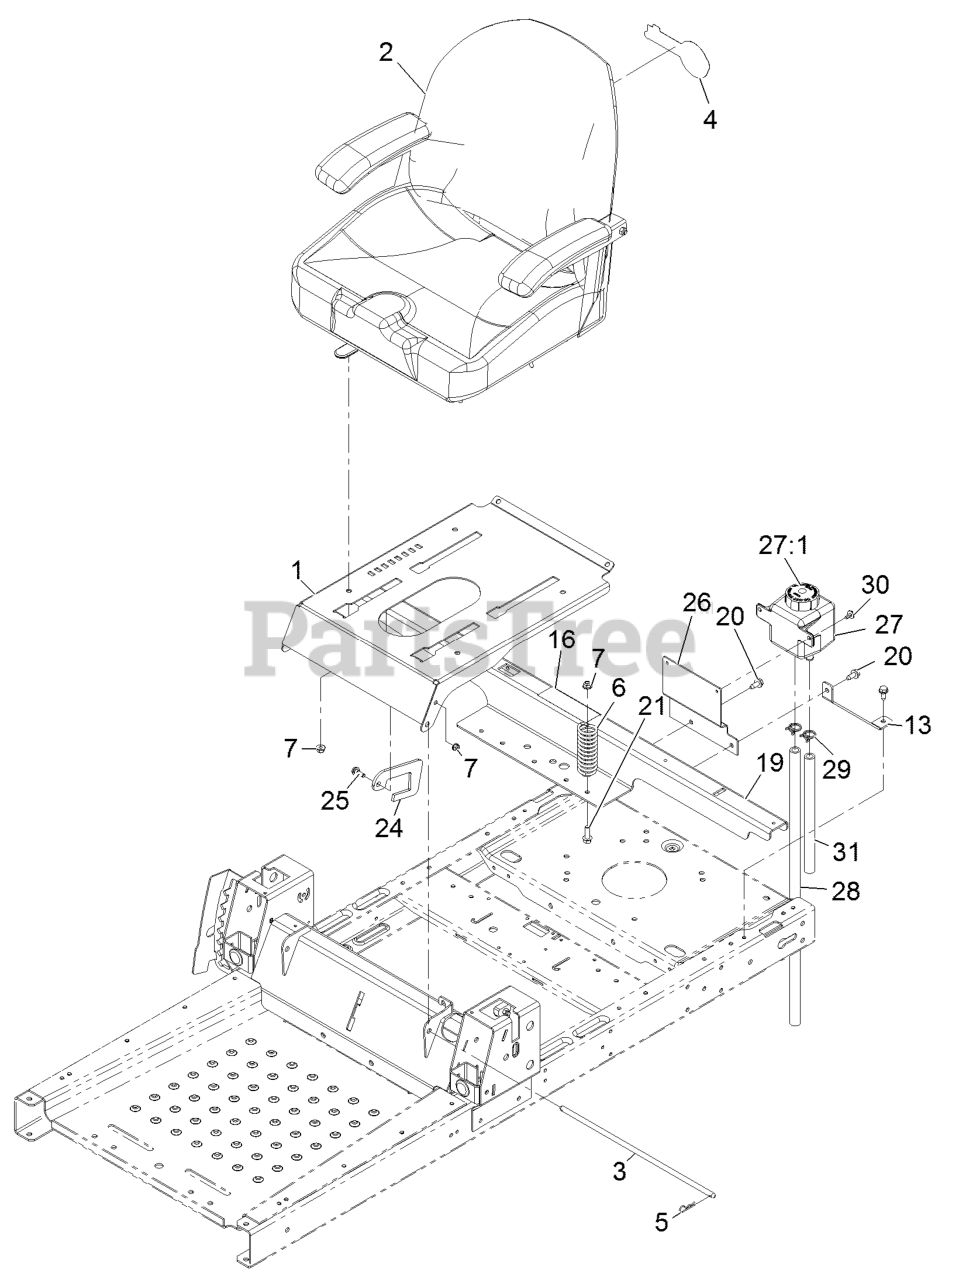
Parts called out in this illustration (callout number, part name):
2	SEAT ASM
3	ROD-STOP
5	PIN-COTTER
6	SPRING-COMPRESSION
7	NUT-HF, NI
13	SUPPORT-TANK, REAR
16	DECAL-SERVICE, CE
19	SUPPORT-POD
20	Screw-HWH 5/16-18 X 3/4 Tf
21	SCREW-HHF
24	STOP-SEAT
25	SCREW-SHOULDER
26	MOUNT-TANK
27	TANK-HYD
27:1	CAP-RESERVOIR, HYD
28	HOSE-OVERFLOW
29	CLAMP-HOSE
30	SCREW-HHFTF
31	HOSE-OVERFLOW
